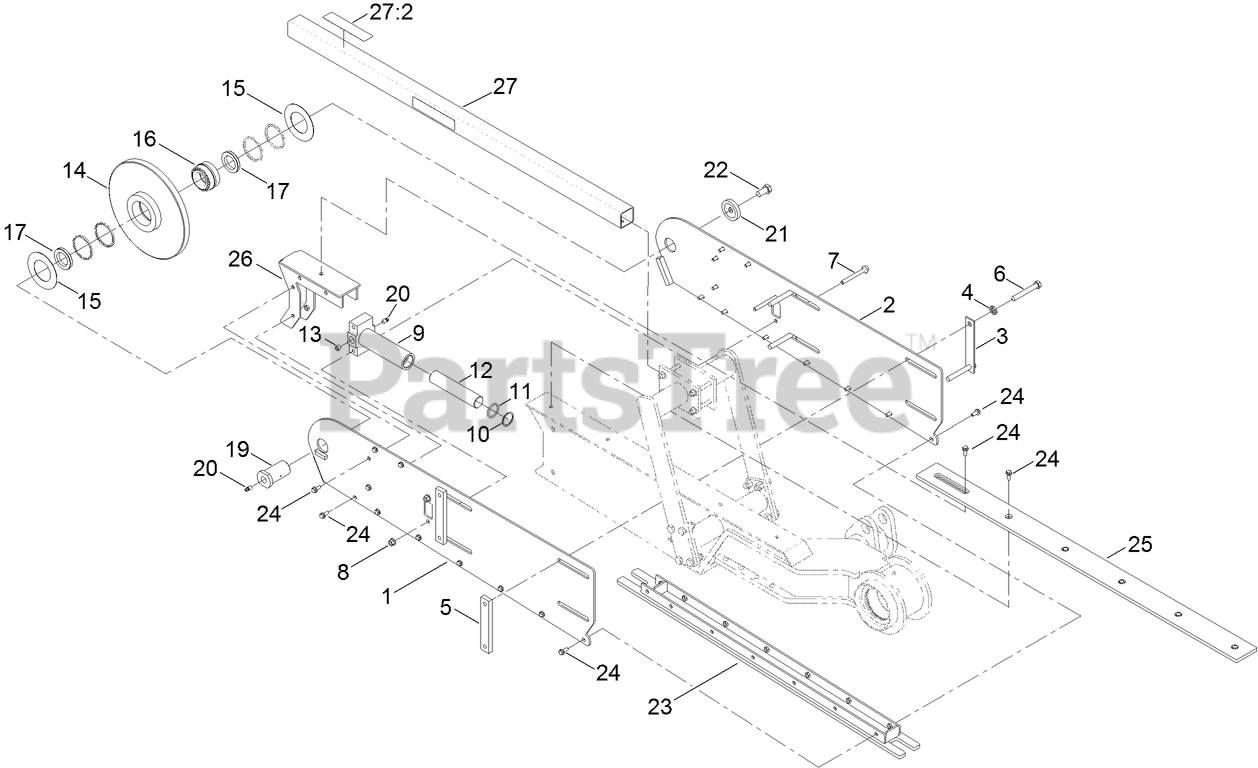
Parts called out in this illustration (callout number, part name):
1	PLATE-BOOM END, RH
2	PLATE-BOOM END, LH
3	BAR-CLAMP
4	WASHER-LOCK
5	BAR-TAPPED
7	BOLT-HHF
8	NUT-LOCK, HHF
9	BOOM END CYLINDER ASM
10	WASHER-BACKUP
12	ROD-BOOM, END (CYLINDER)
13	PLUG-BLEED
14	ROLLER-BOOM END
15	WASHER-BOOM, END (ROLLER)
16	BEARING KIT
17	SPACER-bearing
19	PIN-BOOM
20	FITTING-LUBE, STRAIGHT
23	CHANNEL-WEAR, PAD
24	SCREW-HHF
25	BAR-WEAR PAD, UPPER
26	SHIELD-EXTENSION
27	BAR-RESTRAINT
27:2	DECAL-DANGER, ENTANGLEMENT
